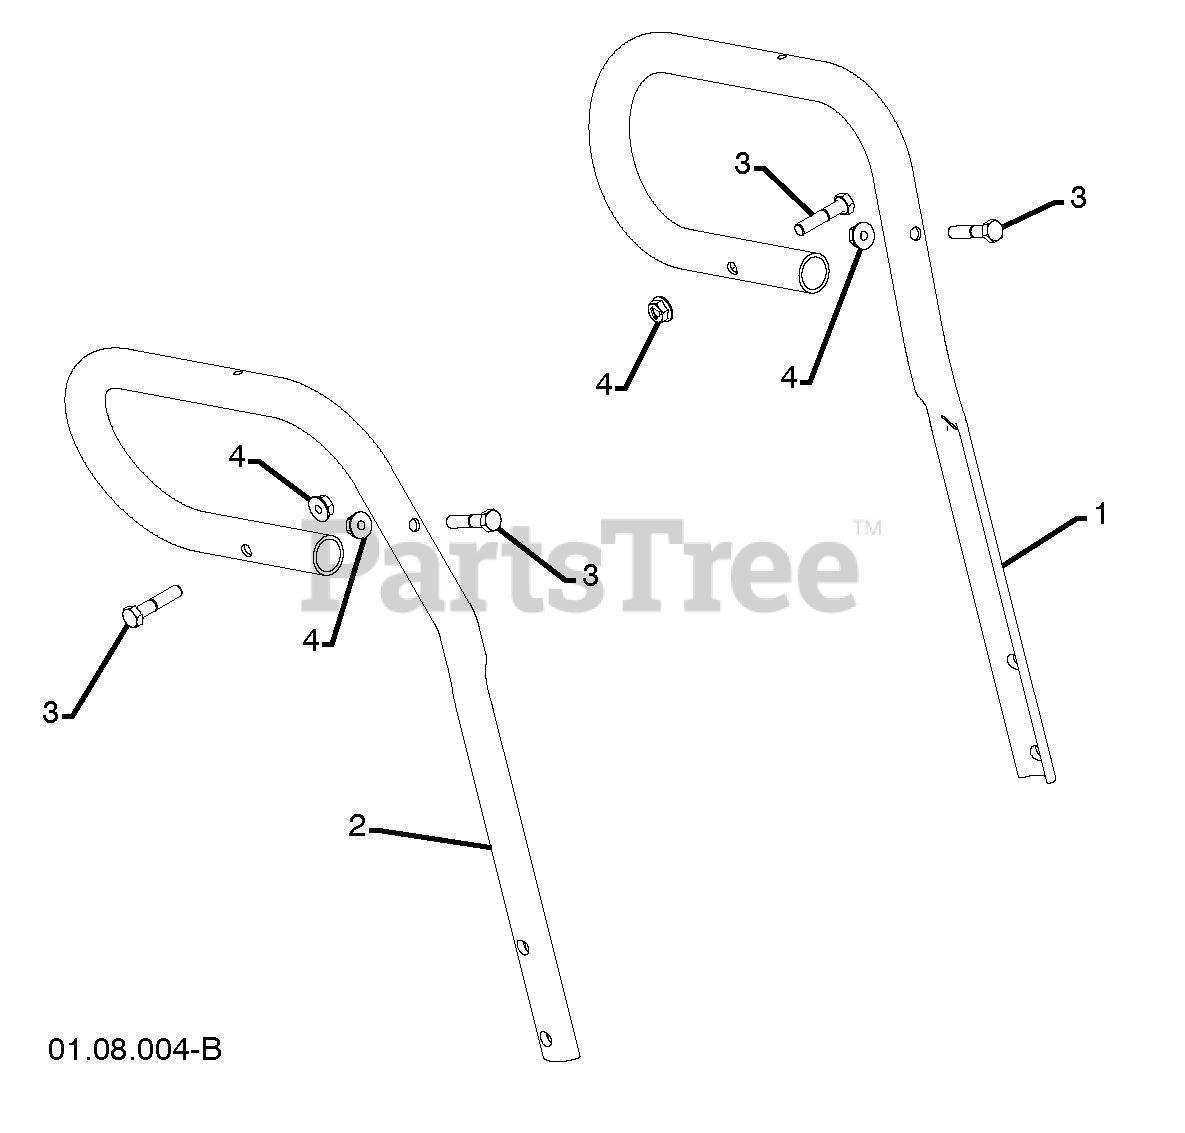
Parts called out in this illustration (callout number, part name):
1	LOOP HANDLE LH
2	LOOP HANDLE RH
3	SCREW 5/16-18 X 1.50
4	NUT 5/16-18
